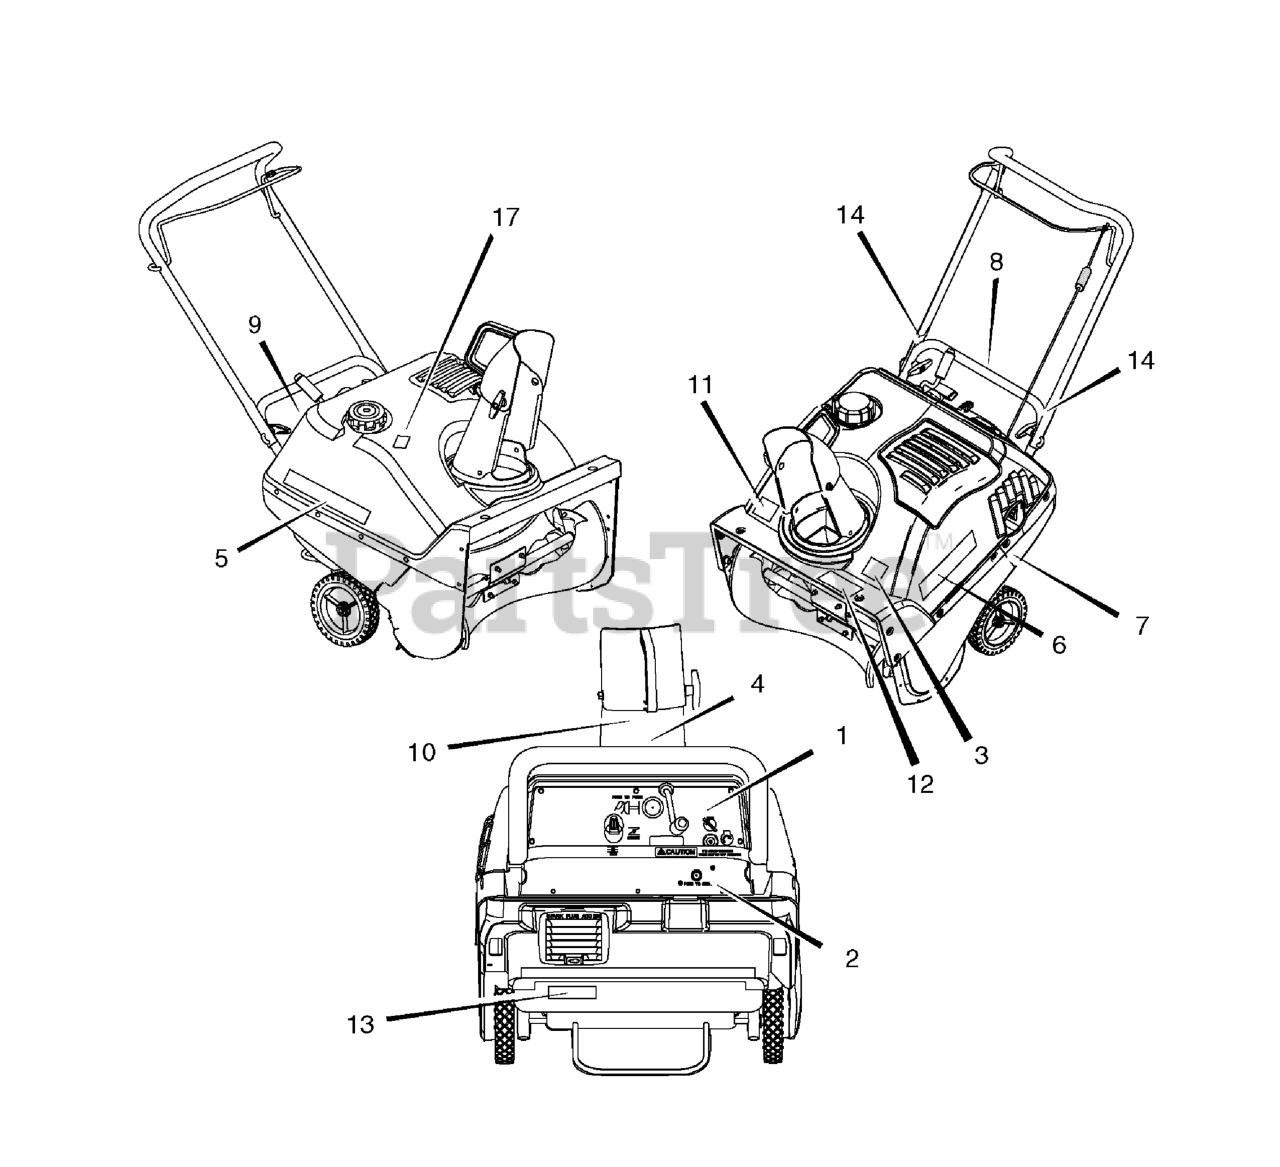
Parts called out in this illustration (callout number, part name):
1	DECAL, Control Panel Electric Start
2	DECAL, Electric Start
3	DECAL, Danger Auger
4	DECAL, Danger Chute
5	DECAL, John Deere R.H.
6	DECAL, John Deere L.H.
7	DECAL, Hot Muffler
8	DECAL, Auger Control
9	DECAL, Choke
10	DECAL, Thrown Objects
11	DECAL, Leaping Deer Logo
12	DECAL, 522E
13	DECAL, Warning, Access Cover
14	DECAL, Handle protector
17	DECAL, Briggs & Stratton Logo
18	MANUAL, Operator's
19	MANUAL, Parts List
